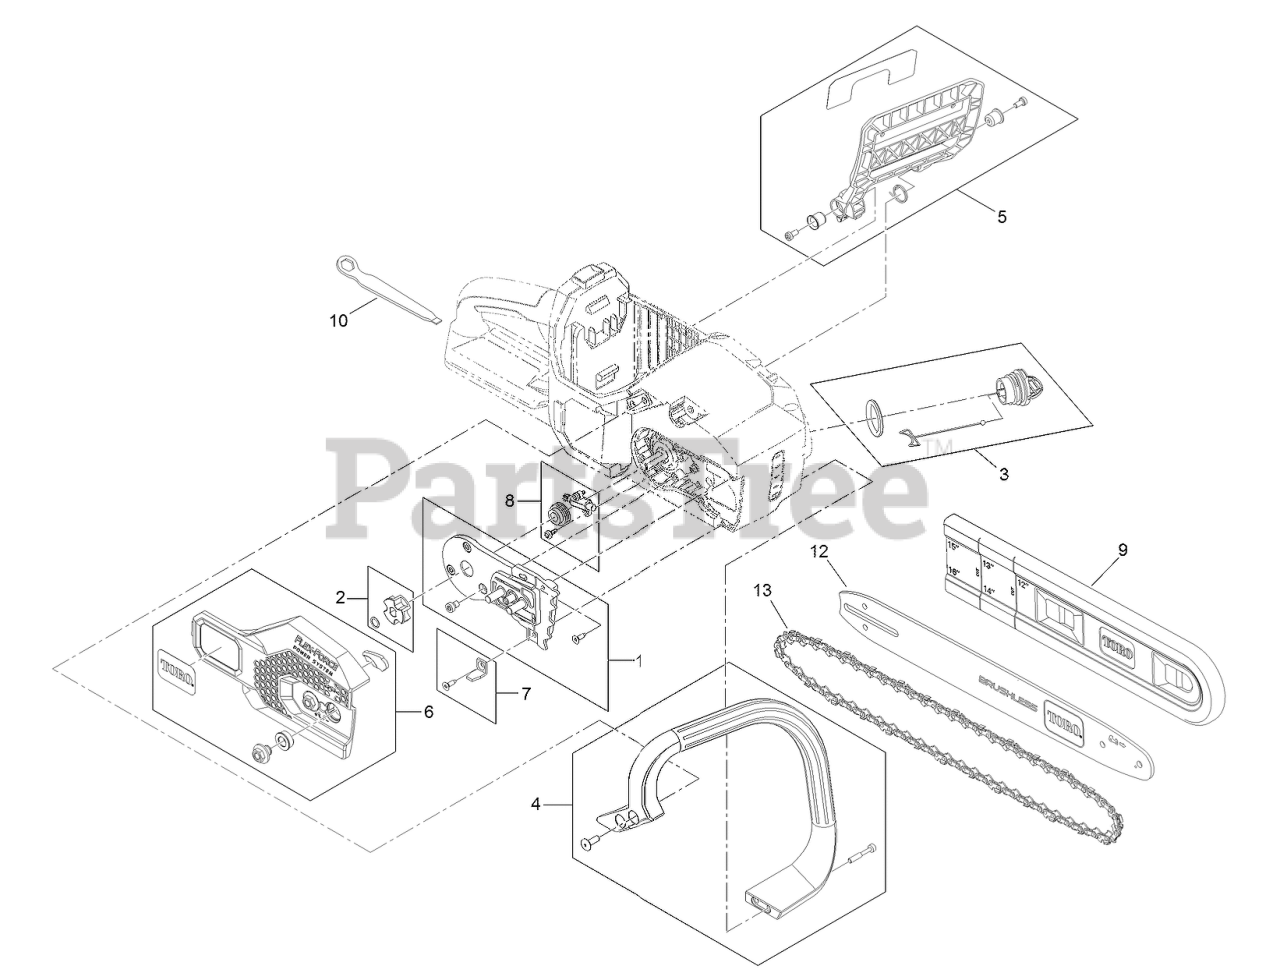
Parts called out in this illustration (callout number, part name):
1	ADJUSTER BAR BRACKET ASM
2	DRIVE GEAR ASM
3	OIL CAP ASM
4	HANDLE ASM
5	CHAIN BRAKE ASM
6	BAR COVER ASM
7	BAR COVER SUPPORT BRACKET ASM
8	OIL PUMP ASM
9	BAR-SLEEVE, CHAINSAW
10	TOOL-ADJUSTMENT, BAR
12	BAR-REPLACEMENT
13	CHAIN
